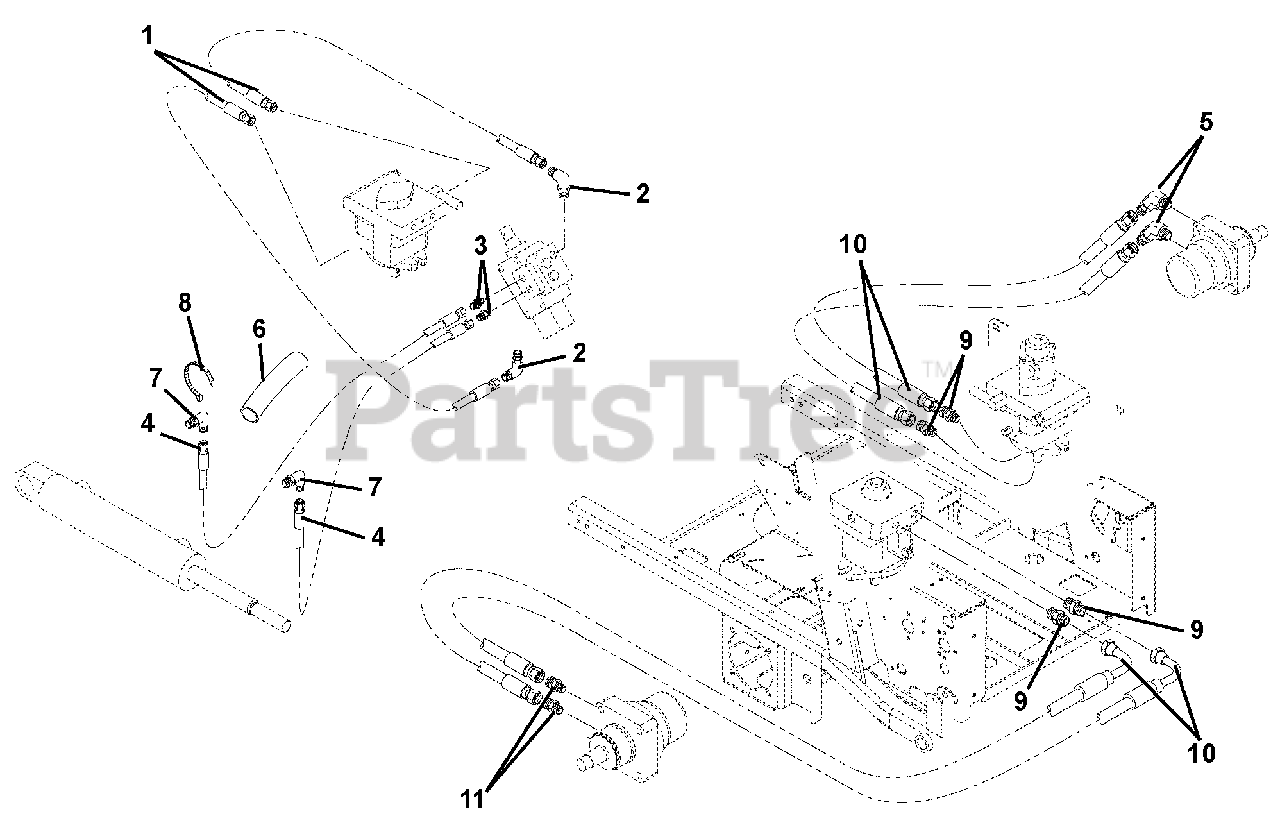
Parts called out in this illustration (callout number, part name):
1	Hose, Hydraulic
2	Hydraulic, Fitting Elbow
4	Hose, Hydraulic
5	Fitting, Hydraulic
6	Sleeve, Protective 24 in.
7	Fitting, Hydraulic
8	Cable Tie
9	Adapter, Face Seal 8 x 8 .50 O-Ring
10	Hose, Hydraulic .50
11	Adapter, Hydraulic Steel .875 to .75
